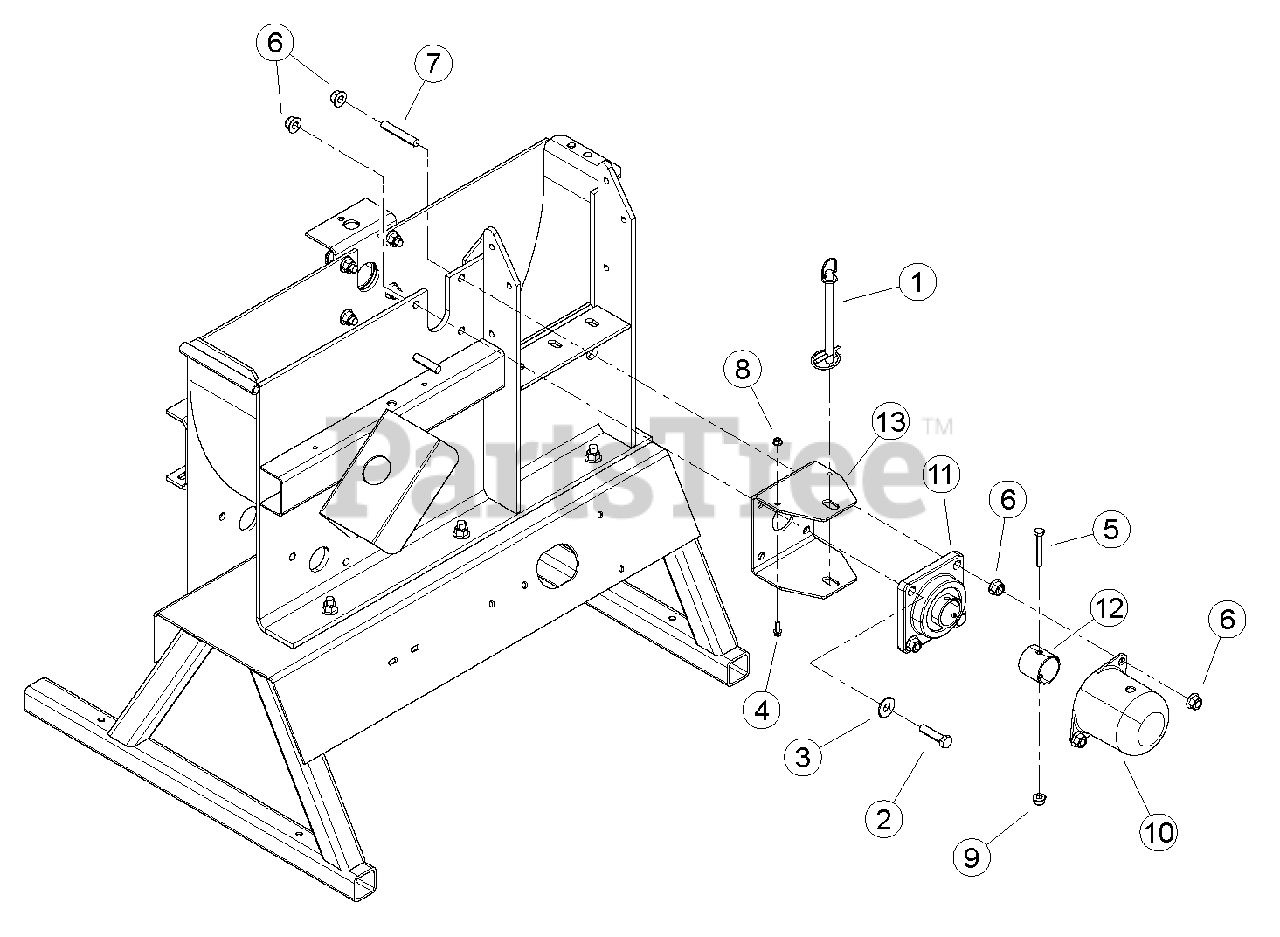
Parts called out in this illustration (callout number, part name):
1	PIN, HITCH 1/2 X 6-1/2 W LYNCH
2	BOLT, 1/2 X 2 GR5 HEX CAPSCREW ZP
3	WASHER, 1/2" FLAT ZP
4	BOLT, 1/4-20 X 3/4 HWH GR5 CZP
5	BOLT, 3/8 X 2-1/2 GR5 HHCS ZP
6	NUT, 1/2-13 NYLOCK FLANGE
7	STUD, 1/2"-13 X 3"LG B7 ZP
8	NUT, 1/4-20 NYLOCK-FLANGE
9	NUT, 3/8-16 NYLOCK FLANGE
10	CAP, LARGE SHAFT
11	BEARING, 1-3/4 4 BOLT FLANGE
12	COLLAR, CHIPPER LOCK
13	BRACKET, ROTOR LOCK
